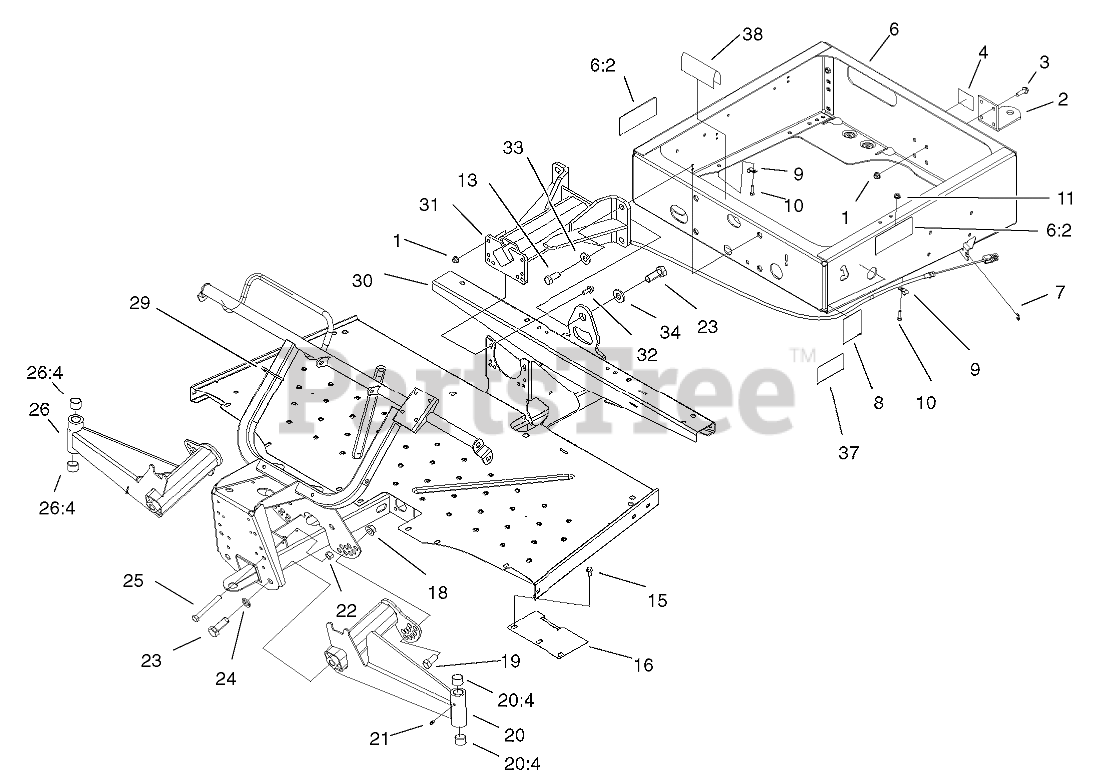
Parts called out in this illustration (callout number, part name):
1	NUT-HF, NI
2	HITCH-DUTY, LIGHT
3	SCREW-HHF
4	DECAL-RATING, HITCH (LIGHT DUTY)
6	REAR FRAME ASM
6:2	DECAL-WARNING
7	RING-RETAINING, EXTERNAL
8	DECAL-INFORMATION, BOXLATCH
9	CLAMP-R
10	SCREW-HH
11	NUT-HF
13	SCREW-HH
15	SCREW-HHF
16	COVER-PEDAL
18	NUT-HF
19	SCREW-HH
20	LH A-ARM ASM
20:4	BUSHING
21	FITTING-GREASE
22	NUT-LOCK, NI
23	SCREW-HH
24	WASHER-LOCK, INT
25	SCREW-HH
26	RH A-ARM ASM
26:4	BUSHING
29	TIE-CABLE
30	FRAME-FRONT
31	PIVOT YOKE ASM
32	SCREW-HHF
33	WASHER-FLAT
34	WASHER-HARDENED
37	DECAL-CAPACITY (CE)
